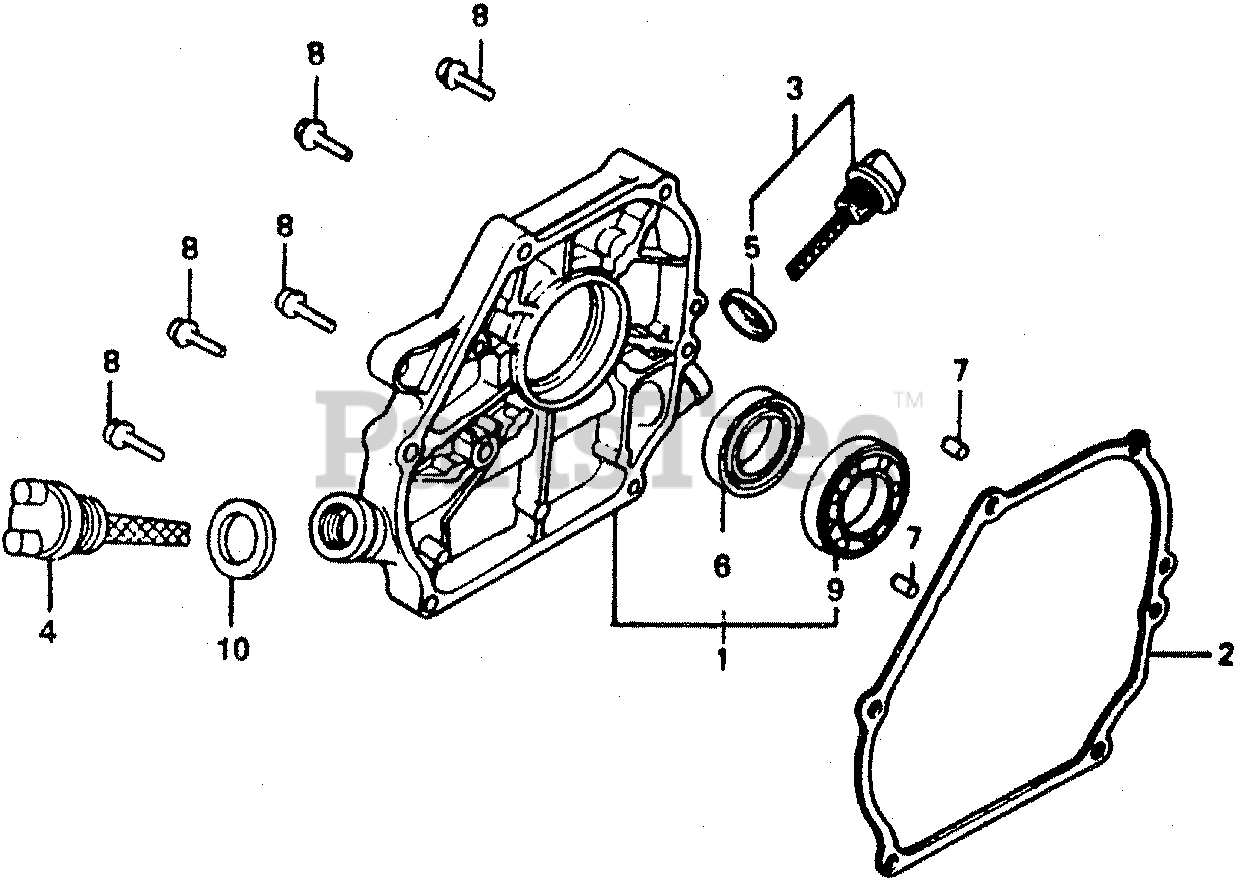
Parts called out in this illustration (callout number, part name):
1	COVER ASSY., CRANKCASE (W-TYPE)
1	COVER ASSY., CRANKCASE
2	GASKET, CASE COVER
2	GASKET, CASE COVER (NON-ASBESTOS)
3	CAP ASSY., OIL FILLER
4	CAP, OIL HOLE
5	GASKET, OIL FILLER CAP
6	OIL SEAL (25X41X6)
7	PIN A, DOWEL (8X14)
8	BOLT, FLANGE (8X32)
9	BEARING, RADIAL BALL (6205)
10	GASKET, OIL FILLER CAP
